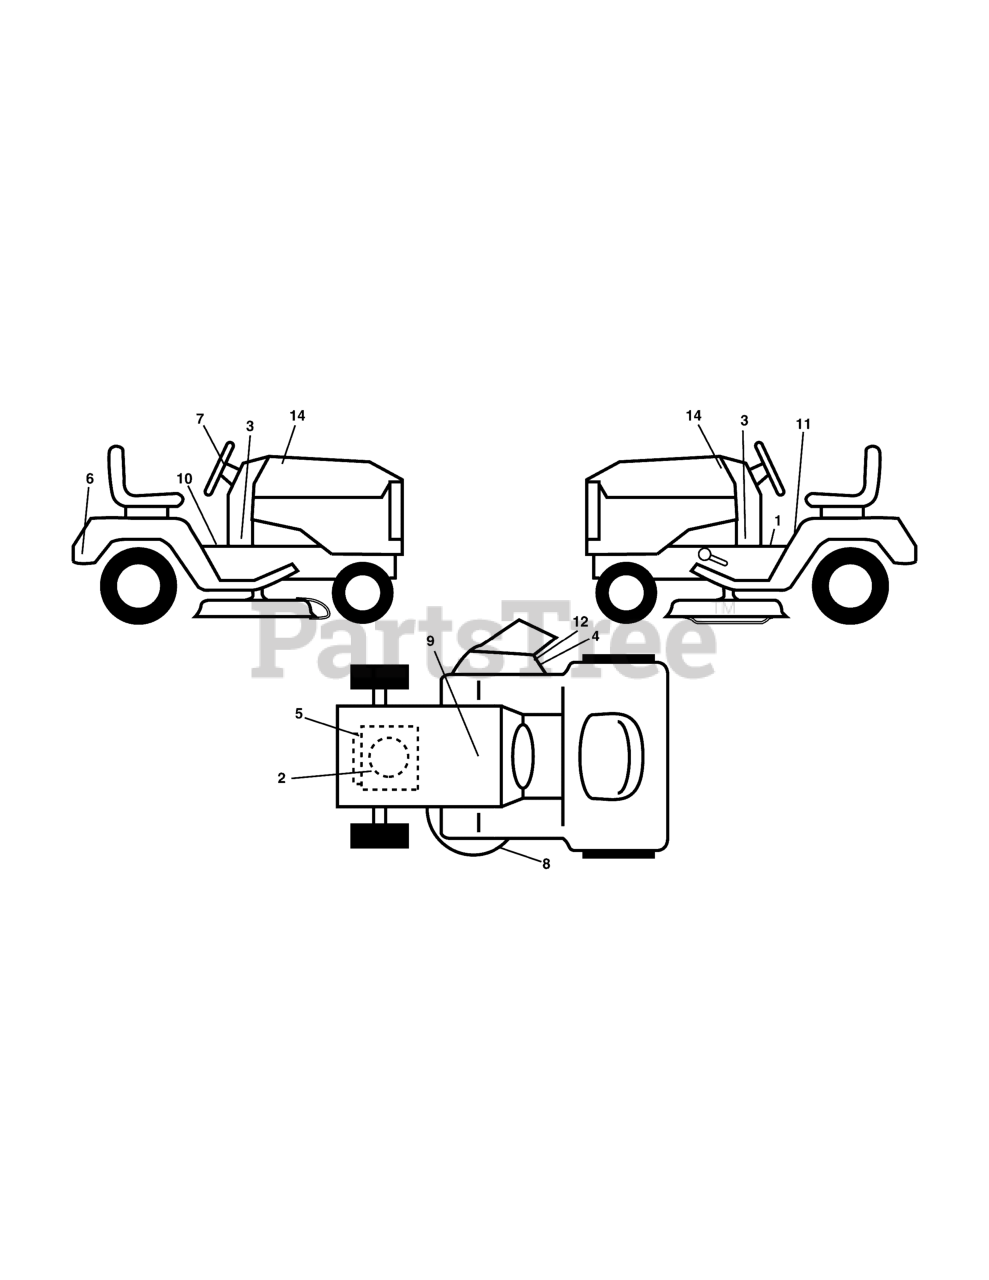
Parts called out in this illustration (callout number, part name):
1	Decal, Saddle Brake Parking
2	Decal, Warning Eng. Sym.
3	Decal, PNL SD
4	Decal, Cutfinger Warning
5	Decal, Engine HP
6	Decal, Fender
7	Decal, Steering Wheel
8	Decal, B-Belt Schematic
9	Decal, Battery Dnge/Poi
10	Decal, Brake/Clutch Symbol
11	Decal, Warning CE
12	Decal, Cutfinger
14	Decal, Hood
